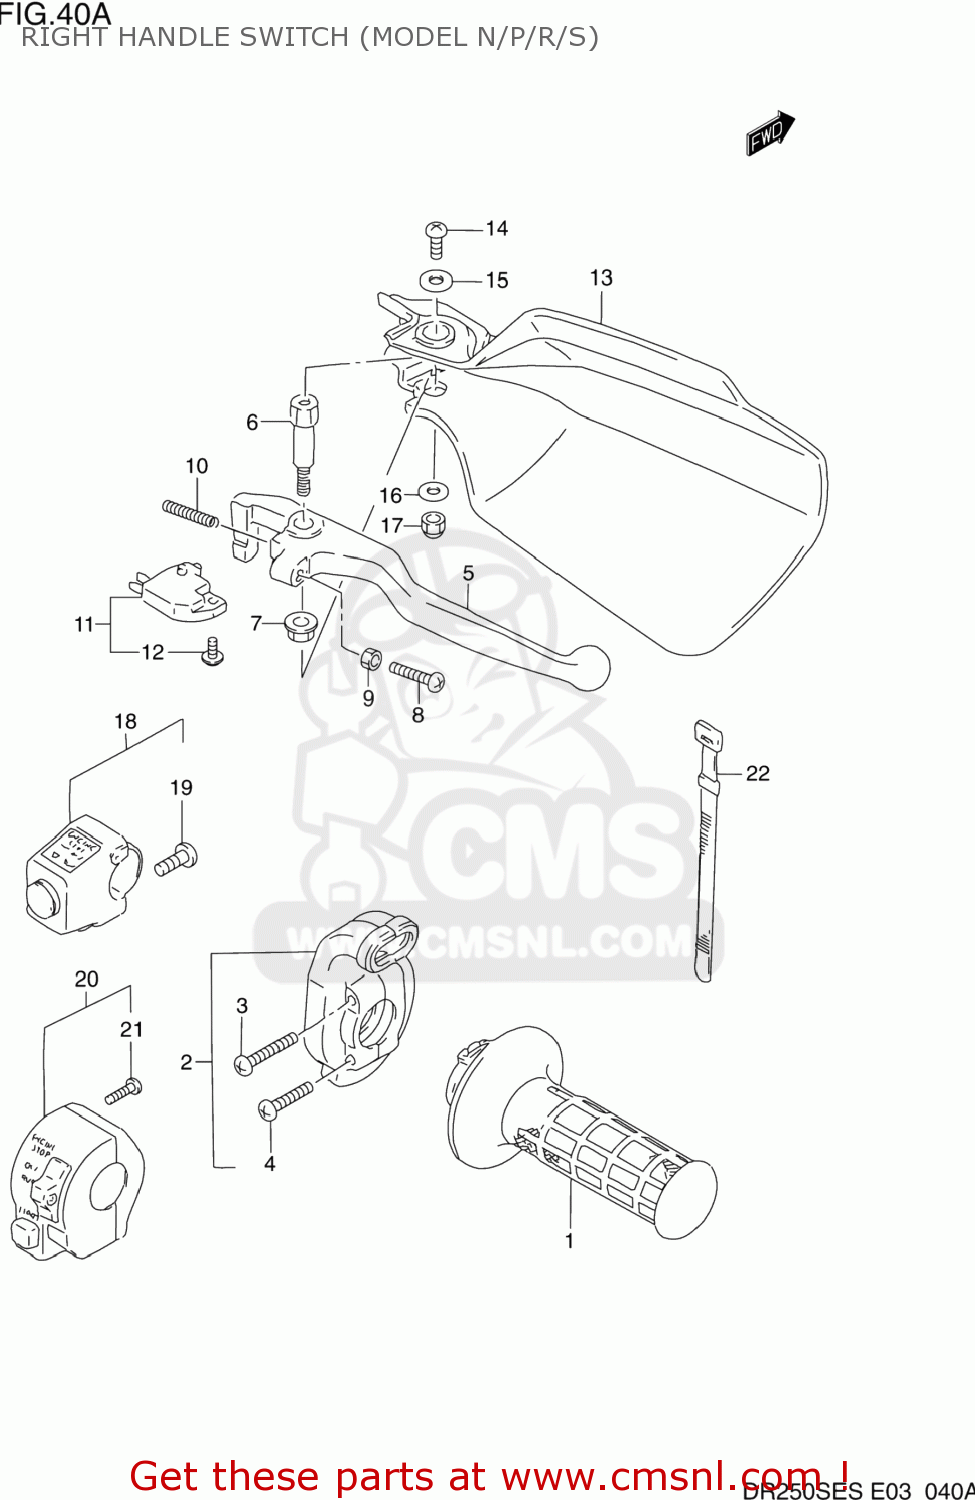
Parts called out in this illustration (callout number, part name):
1	GRIP,THROTTLE
2	CASE ASSY,THROTTLE
3	SCREW(5X25)
4	SCREW 5X20
5	LEVER,BRAKE
6	BOLT,BRAKE LEVER PIVOT
7	NUT 6MM
8	BOLT,ADJUST
9	NUT ,5MM
10	SPRING,RETURN
11	SWITCH ASSEMBLY,STOP
12	SCREW
13	COVER,KNUCKLE,R
14	SCREW(5X10)
15	WASHER (5.5X16X1.2)
16	WASHER (6.5X17X1.6)
17	NUT 6MM
18	SWITCH ASSEMBLY,HANDLE,RIGHT
19	SCREW
20	SWITCH ASSEMBLY,HANDLE,RIGHT
21	SCREW
22	CLAMP(L:120)
